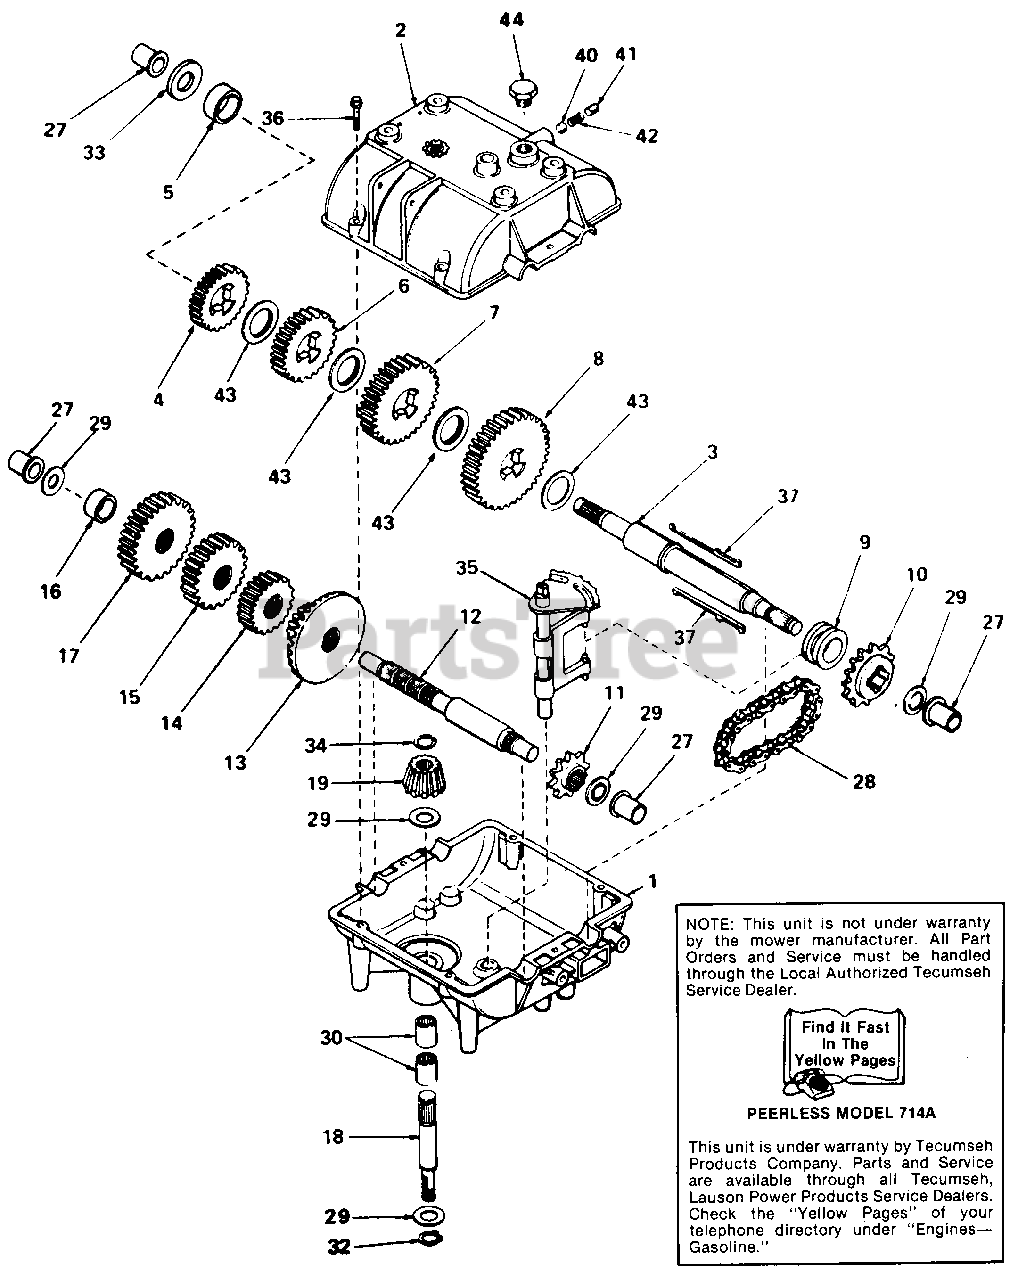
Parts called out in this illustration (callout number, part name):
1	Case, Transmission
2	Cover, Transmission
3	Shaft, Output
4	Gear, Spur (20 Teeth)
5	Gear, Spur (22 Teeth)
6	Gear, Spur (25 Teeth)
7	Gear, Spur (30 Teeth)
8	Gear, Spur (35 Teeth)
9	Collar, Shift
10	Sprocket (18 Teeth)
11	Sprocket (9 Teeth)
12	Shaft, Counter
13	Gear, Bevel (42 Tooth & 15 Tooth Spur Gear)
14	Gear, Spur (20 Teeth)
15	Gear, Spur (25 Teeth)
16	Gear, Spur (28 Teeth)
17	Gear, Spur (30 Teeth)
18	Shaft, Input
19	Bevel Pinion, Input
27	Bushing, Flanged
28	Chain, Roller (No. 41 Chain, 22 Links)
29	Race, Thrust
30	Bearing, Needle
32	Ring, Retaining
33	Washer
34	Ring, Retaining
35	Rod and Fork Ass'y., Shift
36	Screw, Hex Hd. Taptite, 1/4-20 x 1 1/4
40	Ball, Steel, 5/16"
41	Screw, Set, 3/8-16 x 3/8
42	Spring
43	Washer, Thrust
